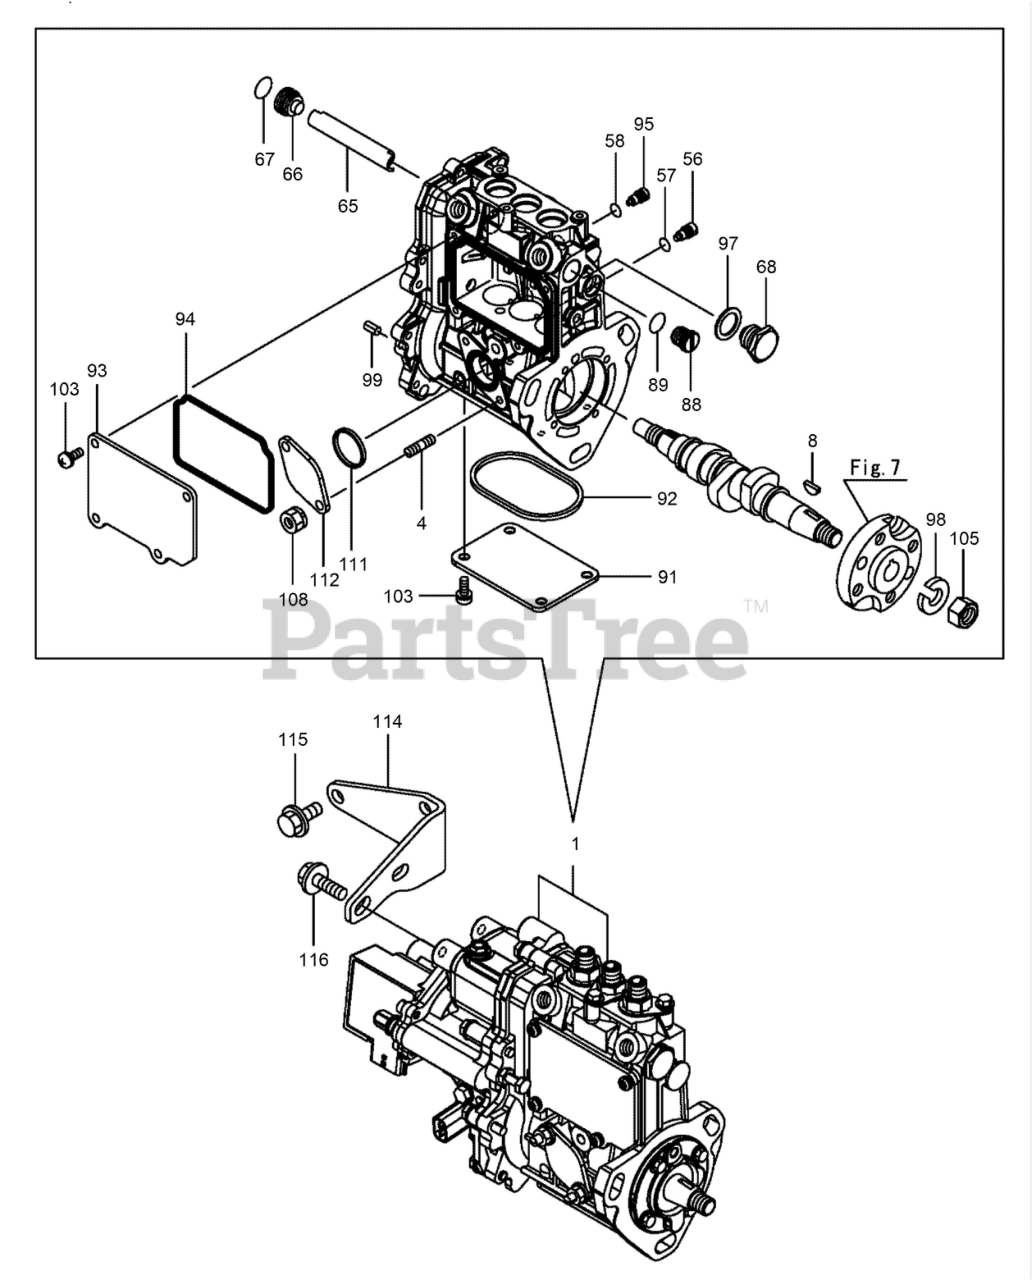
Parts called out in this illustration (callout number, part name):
1	FIE ASSY
4	BOLT-STUD
8	FEATHER KEY-WOODRUFF
56	STOPPER
57	O-RING
58	O-RING
65	DEFLECTOR
66	PLUG-DEFLECTOR
67	O-RING
68	PLUG-DEFLECTOR
88	PLUG-RACK
89	O-RING
92	GASKET
94	GASKET
95	STOPPER-RACK
97	WASHER-SEAL
98	WASHER-SPRING
99	PIN-SPRING
111	GASKET
112	COVER-PUMP
114	SUPPORT
